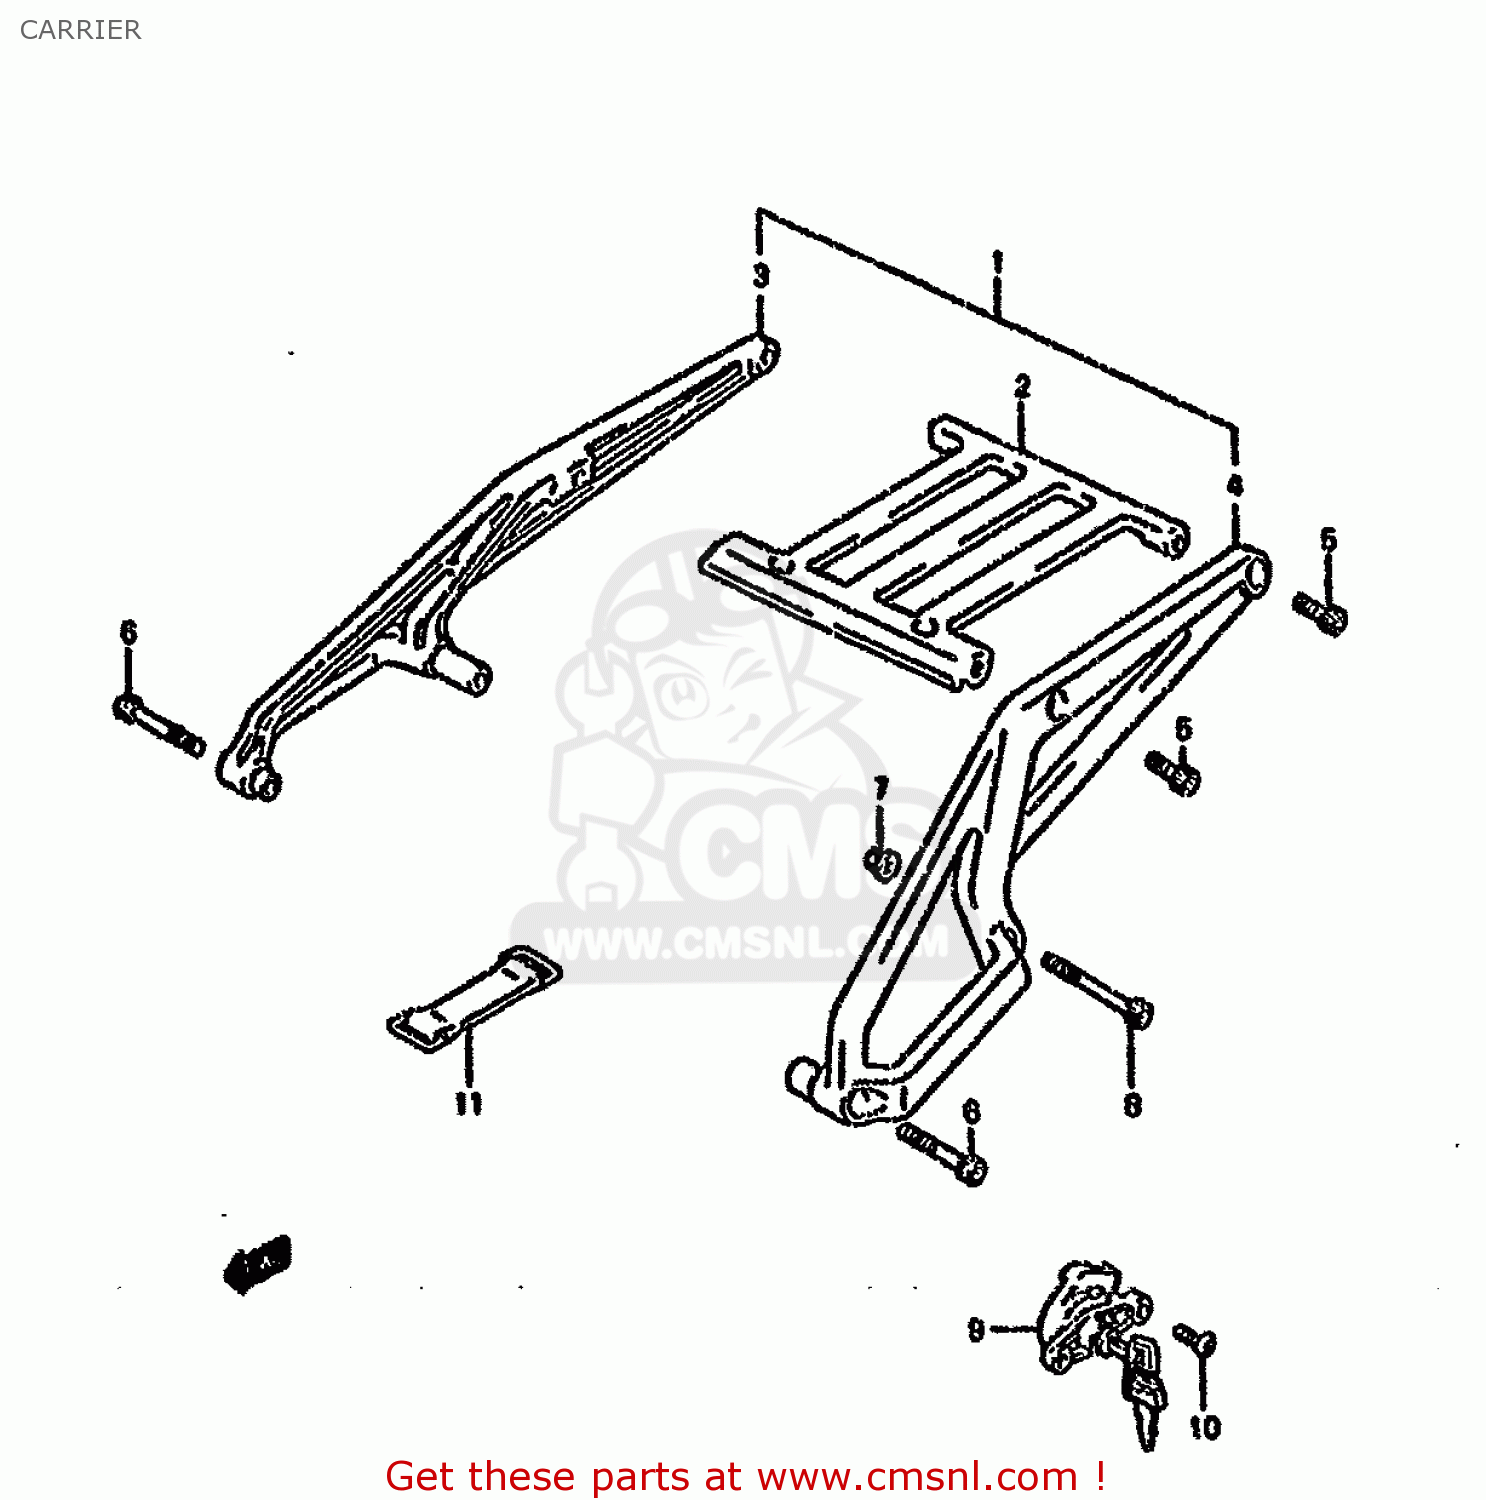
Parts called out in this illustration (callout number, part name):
1	CARRIER,REAR (SILVER)
2	REAR CARRIER,CENTER (SILVER)
3	REAR CARRIER,RH (SILVER)
4	CARRIER,RR,L(SILVER)
5	BOLT
6	BOLT(8X50)
7	NUT
8	BOLT,REAR
9	LOCK SET,SEAT
10	SCREW
11	BAND
